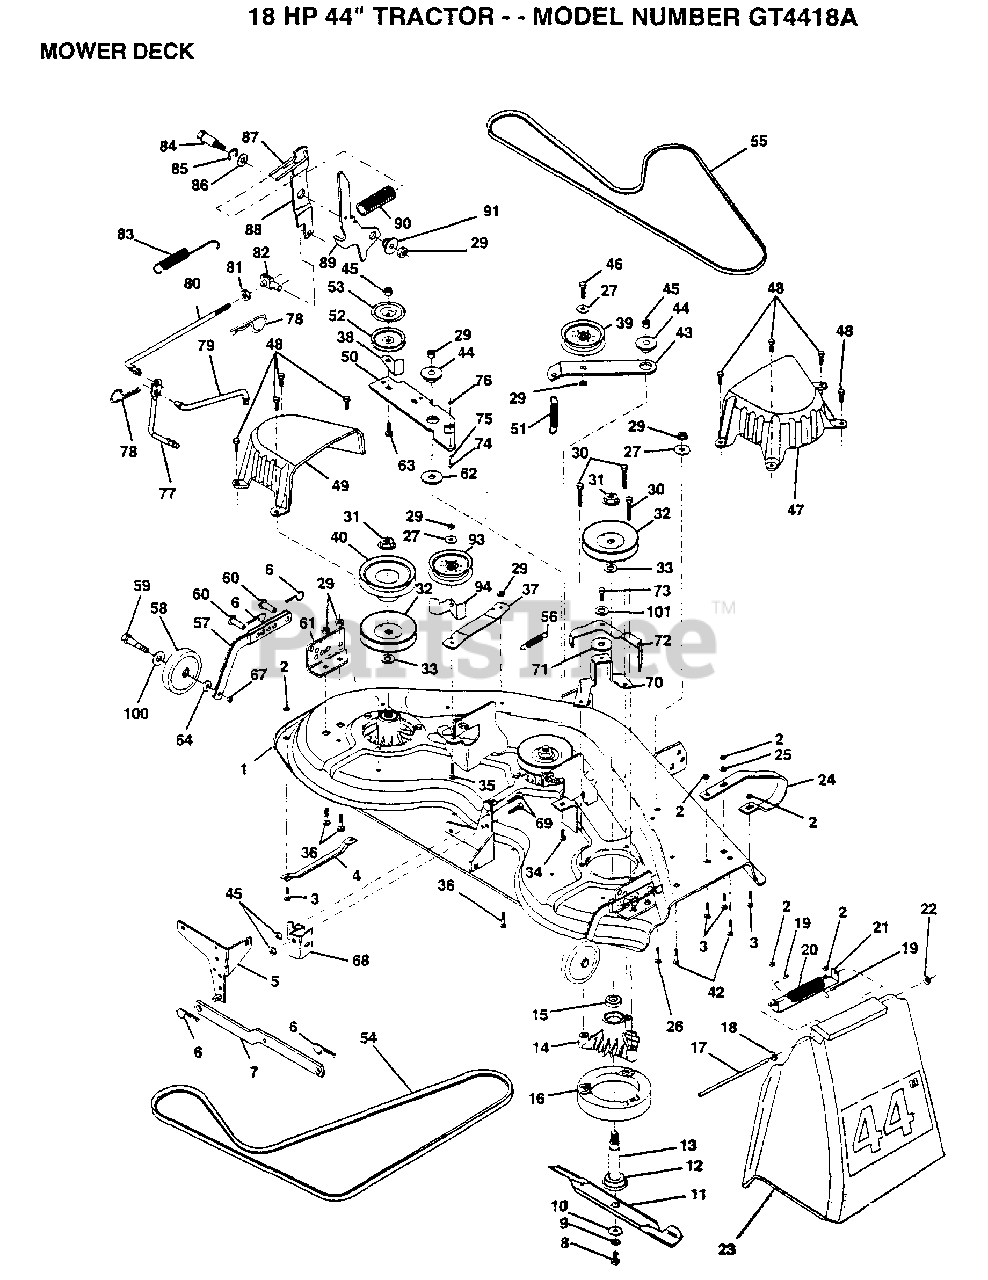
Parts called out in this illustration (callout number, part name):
1	"DECK ASM WELD44"""
2	NUT
4	RUNNER-LH M
5	BRKT.ASM.SW.44/50
8	BLADE BOLT
10	WASHER.HARD.BLADE
11	"BLADE.44"" HIPERF"
12	BEARING.BALL
13	SHAFT.ASM.W/BRNG
14	HOUSING.MAND.44.V
15	BEARING
17	ROD-HINGE T
18	WASHER
19	CAP-SLEEVE LT
20	SPRING TORSION
21	BRKT DEFLECTOR
22	NUT PUSH M
23	DEFLECTOR SHIELD
24	RUNNER.RH
25	WASHER M
26	BOLT
27	WASHER
29	NUT
33	WASHER
34	BOLT.3/8-14X1.25
35	BOLT
36	BOLT D
37	STIFFENER.ARM.IDL
38	KEEPER BELT IDLER
39	FLAT IDLER PULLEY
40	"PULLEY.DRIVEN.44"""
42	BOLT
43	"ARM.IDLER.SEC.44"""
44	SPACER RETAINER
47	"COVER.MAND.RH.44"""
48	SCREW.1/4-20X5/8
49	COVER.MANDREL.LH
50	ARM.IDLER.PRIMARY
51	"SPRING.SEC.44""VEN"
52	PULLEY.IDLER.VGRO
53	SHIELD.IDLER.44.V
54	BELT-V MOWER PRIM
55	BELT-V.88.12.MW
56	"SPRING,EXTENTION"
57	BAR.ASM.GUAGE.WHL
58	WHEEL.GAGE.BLK.PL
59	BOLT M
60	PIN.CLEVIS
61	BRACKET.GUAGE.WHL
62	HARDENED WASHER
63	BOLT.3/8-16X1.50
64	WASHER
67	LOCKNUT
68	BRACKET PVT MCH
70	"BRACKET SUPT 44"""
71	HARD SMALL WASHER
72	ARM BRAKE ASM
73	BOLT.SHLD.5/16-18
75	SHOULDER BOLT
76	LOCKNUT
77	PIVOT ROD
78	RETAINER M
79	ROD CLUTCH SECON
80	ROD.CLUTCH.PRIM44
81	NUT
82	TRUNION ADJ
83	SPRING EXT
84	SHOULDER BOLT
85	RING
86	WASHER
87	SPRING KEEPER
88	CLUTCH ARM SECOND
91	BUSHING
93	IDLER-FLAT T
100	WASHER
101	HARD SMALL WASHER
